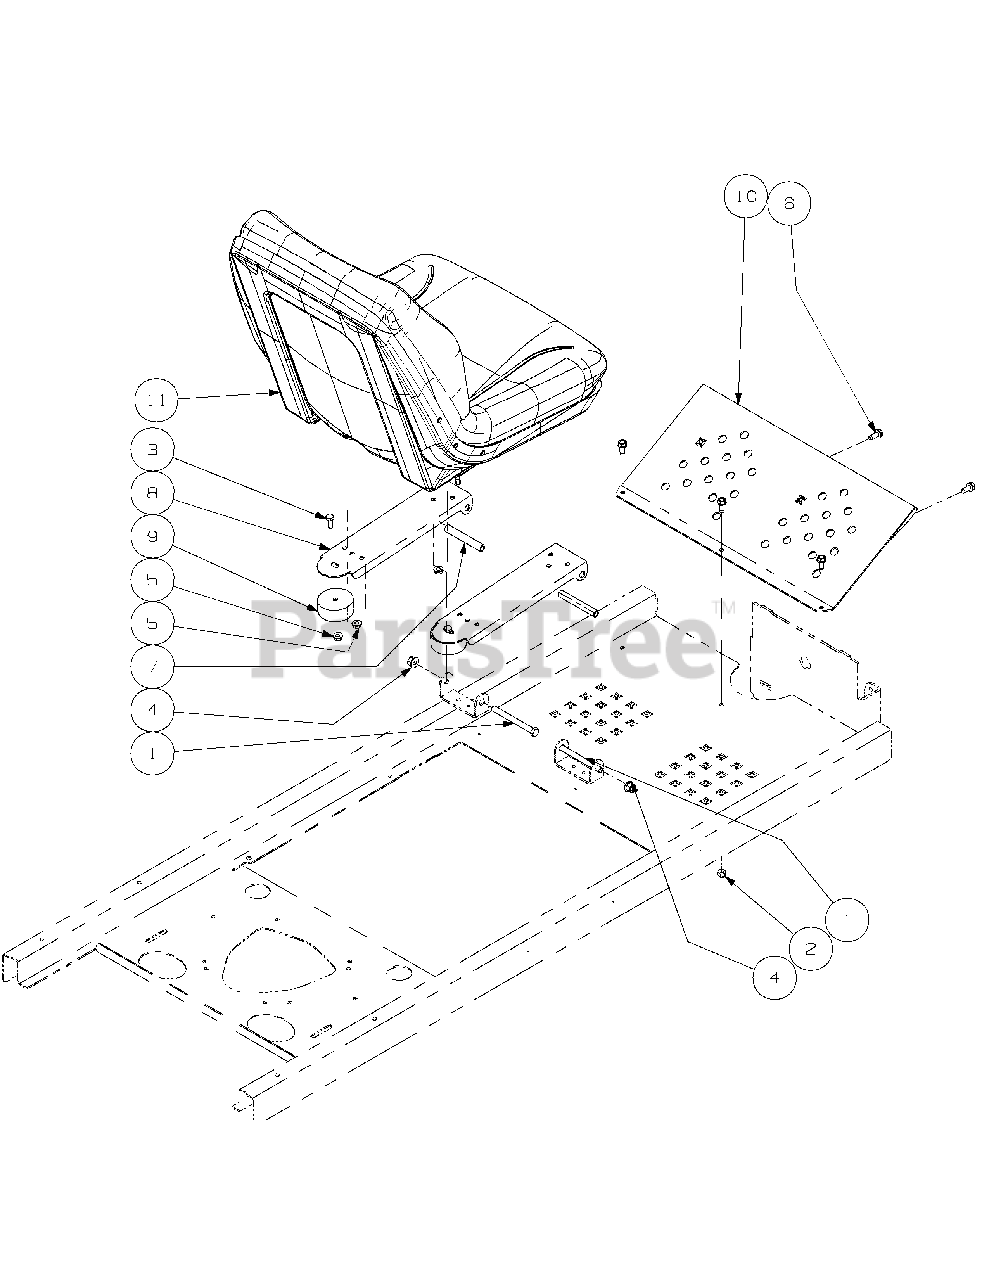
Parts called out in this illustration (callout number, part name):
1	Hex Cap Screw, 3/8-16, 4.00
2	Nylock Nut, 5/16-18
3	Hex Cap Screw, 5/16-18 x .75
4	Flange Lock Hex Nut, 3/8-16
5	Nut, 5/16-18, Hex Flange Lock
6	Self Tapping Screw 5/16-18 x .750
7	Spacer, .370 ID x .500 OD x 3.45
8	Seat Mounting Bracket
9	Bumper, 2.50 OD x 1.13 Long
10	Foot Rest Bracket
